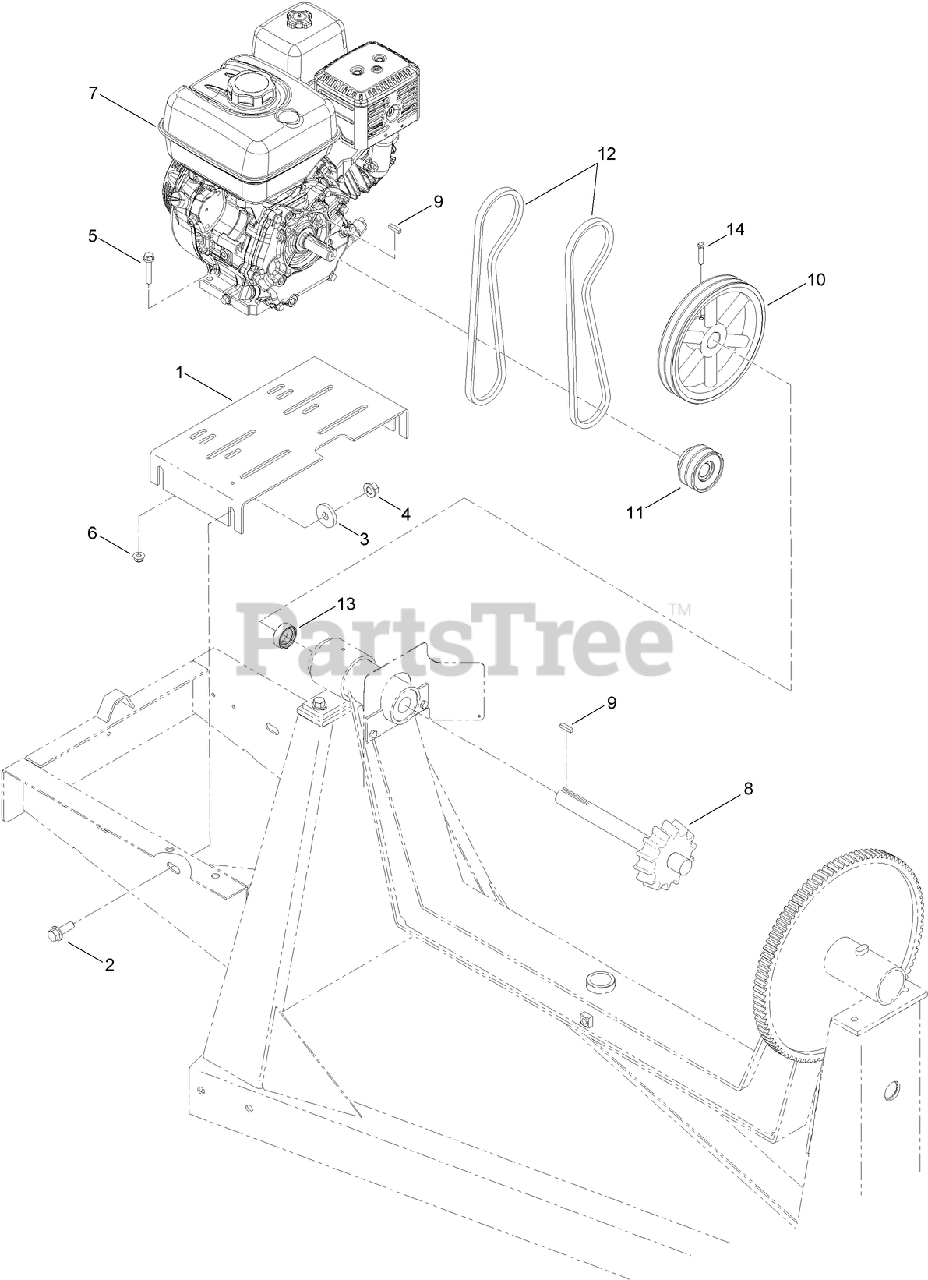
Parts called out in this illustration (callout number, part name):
1	BASE-MOTOR
2	SCREW-HHF
3	WASHER-FLAT
4	NUT-LOCK
5	SCREW-HHF
6	NUT-HF, NI
7	ENGINE-HONDA, GX240
8	SHAFT-DRIVE
11	SHEAVE
12	BELT-V
13	COLLAR-LOCKING
14	SCREW-SET
